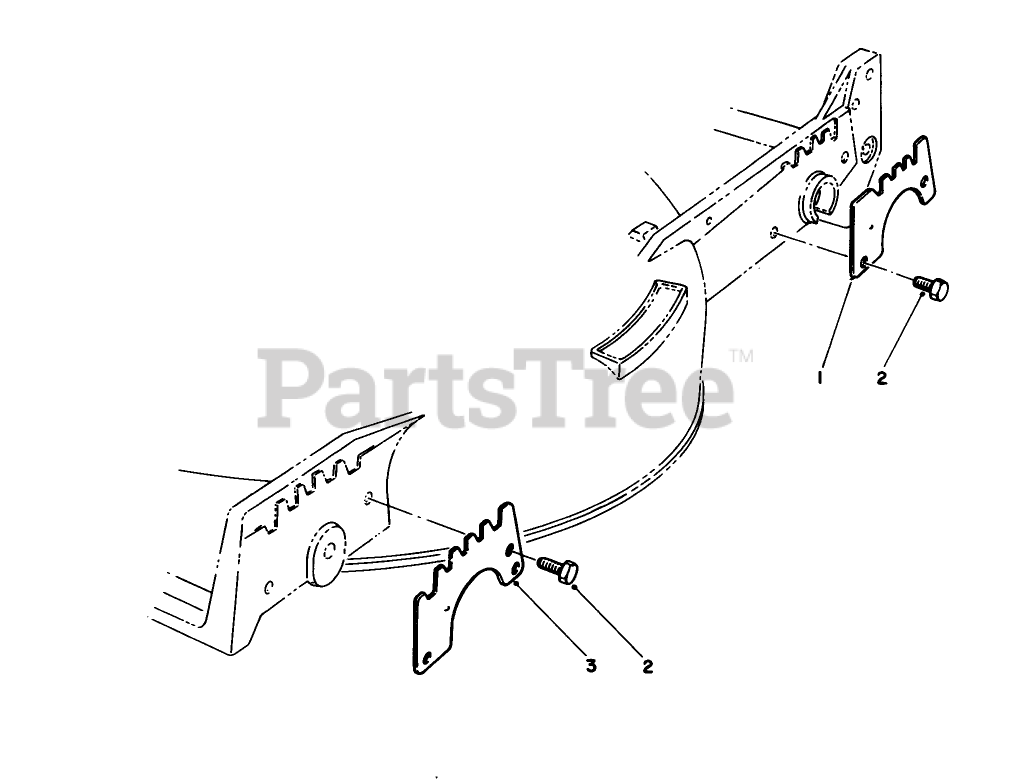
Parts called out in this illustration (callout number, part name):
1	WEAR PLATE,REAR
2	SCREW-HWH
3	WEAR PLATE
